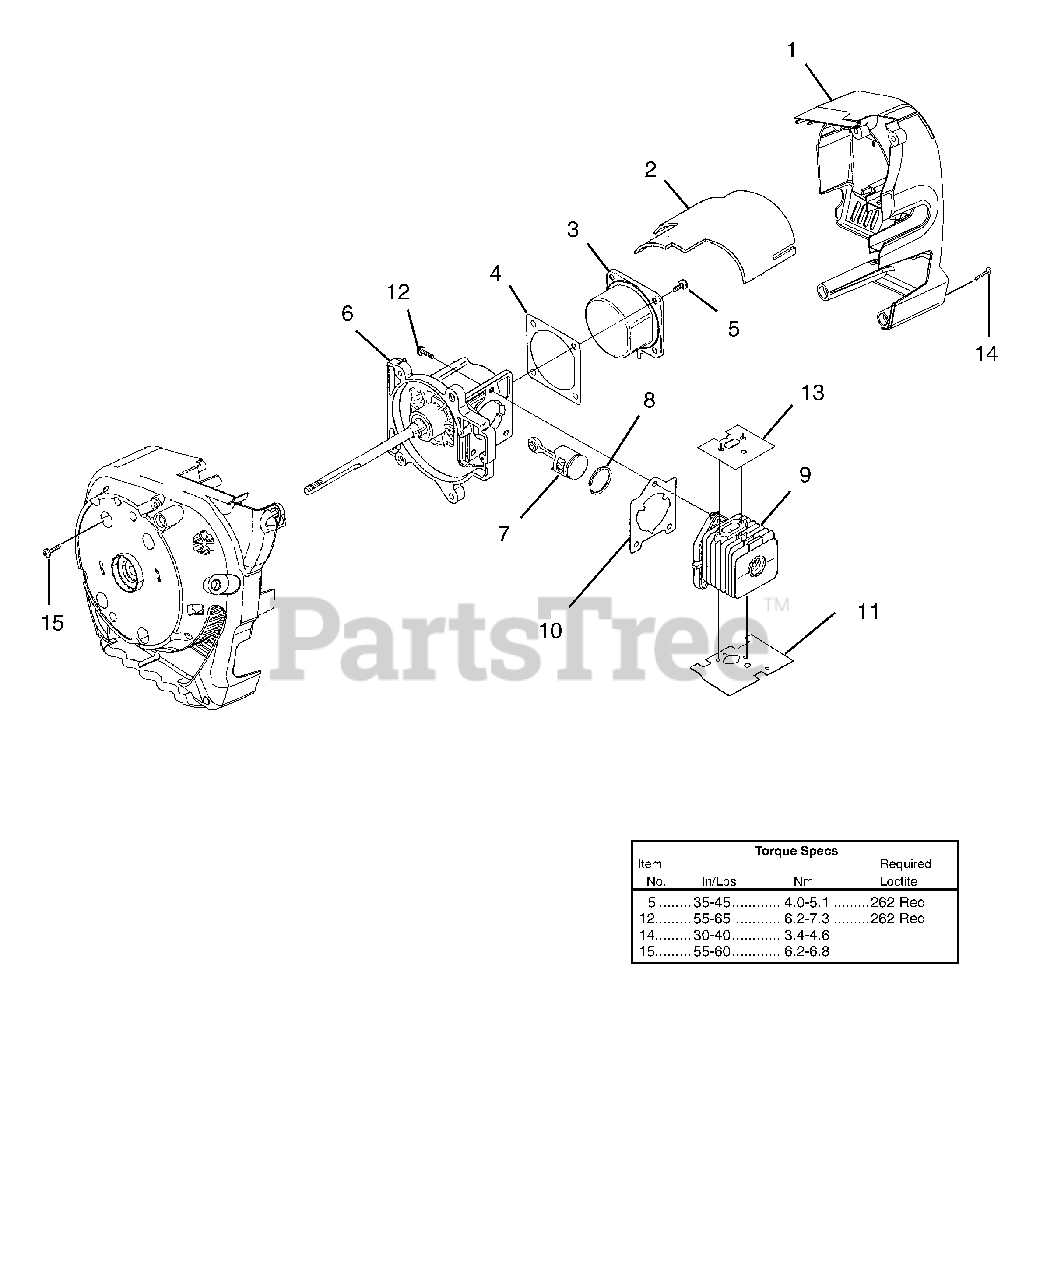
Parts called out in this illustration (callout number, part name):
1	Shroud
2	Heat Shield, Muffler
3	Crankcase Cover Kit
4	Gasket, C/Case
5	Screw, Sems (10-24 x .560)
6	Short Block (Svc) (25cc)
7	Piston & Rod (25cc)
8	Piston Ring (25cc)
9	Cylinder Kit (25cc)
10	Gasket, Cylinder
11	Gasket, Heat Dam
12	Screw, Sems (12-24 x 3/4 in.)
13	Gasket, Muffler
14	Screw, Thread Forming (10-14 x 7/8 in.)
15	Taptite, Truss (10-24 x 3/4 in.)
